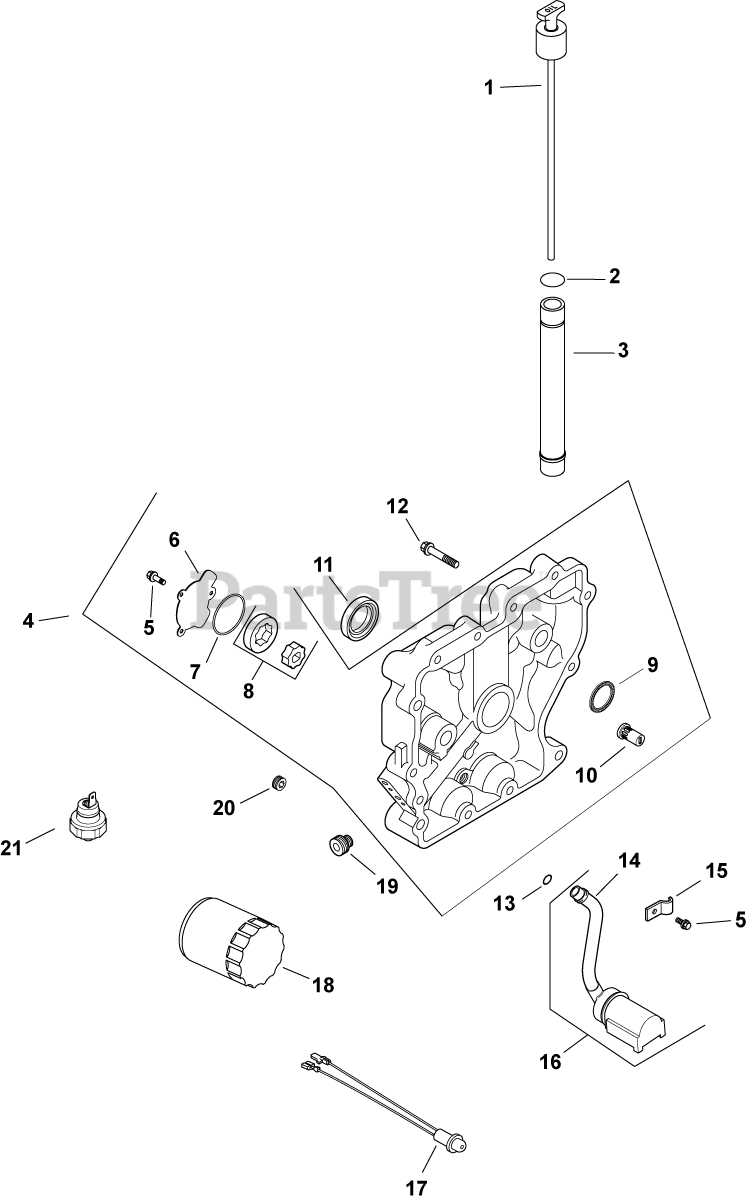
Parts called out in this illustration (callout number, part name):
1	KIT, OIL FILL TUBE - METAL
4	CLOSURE PLATE ASSEMBLY
5	SCREW,FLG THD FRM M5X0.8X16-(#25086398S)
6	COVER, OIL PUMP
7	O-RING (1.78" DIA)
8	PUMP ASSEMBLY, OIL
9	BEARING, CRANKSHAFT
10	VALVE, OIL PRESSURE RELIEF
11	SEAL, OIL
12	SCREW, FLG M8X1.25X45
13	O-RING (.5" DIA)
14	PICK-UP, OIL SCREEN
16	KIT, OIL PICK-UP
17	LIGHT, INDICATOR
18	OIL FILTER
19	NIPPLE, OIL FILTER
20	PLUG, CTSK PIPE 1/8"
21	SENSOR, OIL PSI
